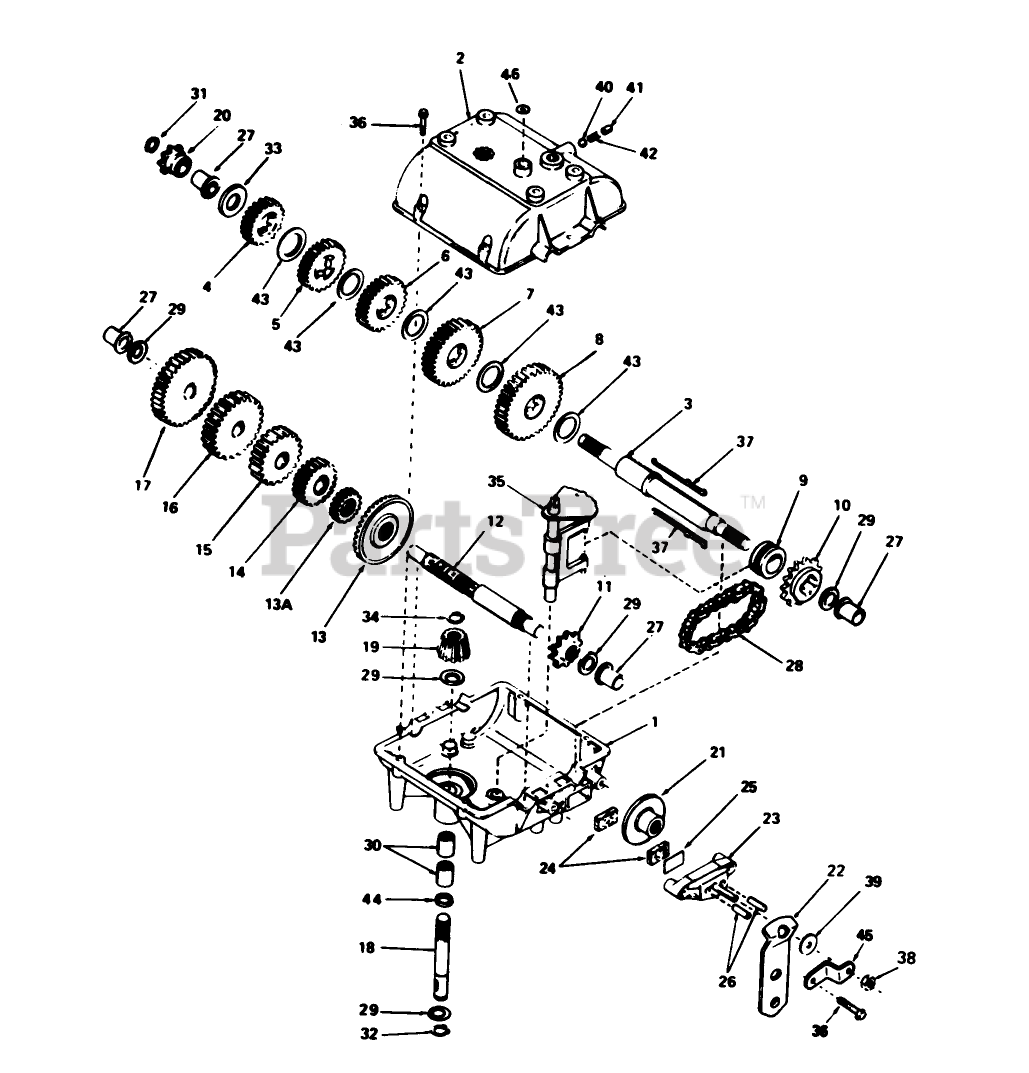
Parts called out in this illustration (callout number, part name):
1	Case-Transmission
2	Cover-Transmission
3	Shaft-Output Brake
4	Gear-Spur 20 teeth
5	Gear-Spur (22 teeth)
6	Gear-Spur, 25 Teeth
7	Gear-Spur, 30 Teeth
8	Gear-Spur, 35 Teeth
9	Collar-Shift
10	Sprocket-18 Teeth
11	Sprocket-9 Teeth
12	Countershaft
13	Gear-Bevel (42Teeth)
13A	Gear-Spur 15 Teeth
14	Gear-Spur, 20 Teeth
15	Gear-Spur, 25 Teeth
16	Gear-Spur (28 teeth)
17	Gear-Spur (30 teeth)
18	Shaft-Input
19	Bevel Pinion-Input
20	Sprocket (8 teeth)
22	Lever-Brake
23	Nozzle-Carburetor
24	Brake Pad
25	Brake Pad Plate
26	Dowel Pin
27	Bushing-Flange
28	Chain-Roller #41
29	Washer
30	Bearing-Needle
31	Piston Asm (.020 O S)
32	Ring-Snap
33	Washer
34	Ring-Retainer
35	Rod and Fork ASM
36	Ring Set (.020 O S)
38	Locknut
39	Washer
40	Ball-Steel
41	Screw-Set
42	Spring
43	Washer
44	O Ring
45	Bracket
46	Cut Seal-Square
